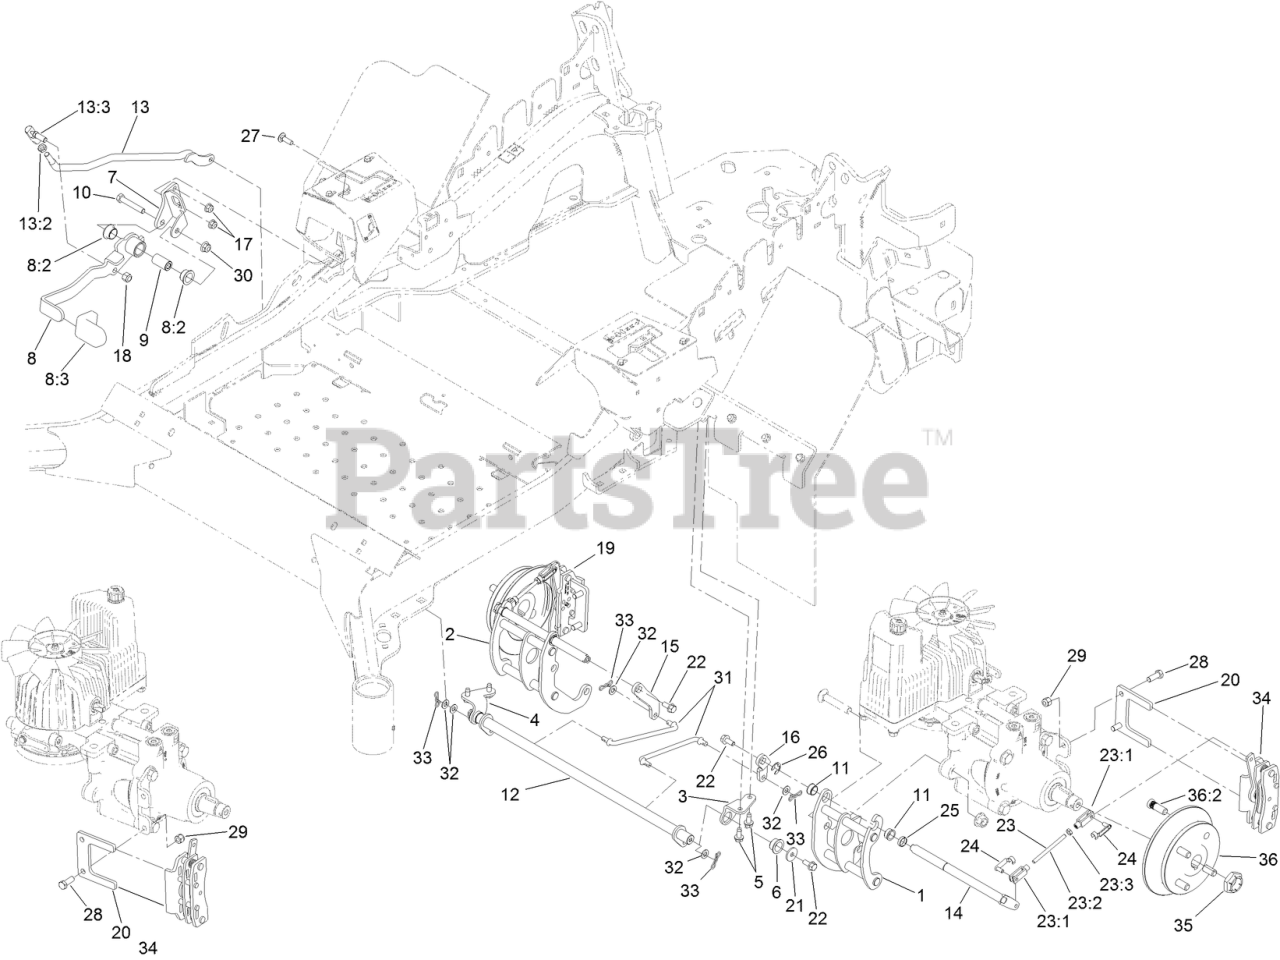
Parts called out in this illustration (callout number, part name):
1	MOUNT-BELLCRANK, LH
2	MOUNT-BELLCRANK, RH
3	MOUNT-PIVOT, LH
4	MOUNT-PIVOT, RH
5	SCREW-HWHTF
6	BUSHING-FLANGE
7	BRACKET-MOUNT
8	BRAKE LEVER ASM
8:2	BUSHING-FLANGE
8:3	GRIP-LEVER
9	HANDLE-PIVOT, BRAKE
10	SCREW-HH
11	BUSHING
12	SHAFT-CROSS
13	FRONT LINKAGE ASM
13:2	END-TIE ROD, RH
13:3	NUT-HJ
14	BELLCRANK,
15	ARM-INNER, RH
16	ARM-INNER, LH
17	NUT-HF, NI
18	NUT-LOCK
19	CALIPER-BRAKE, RH
20	PLATE-MOUNT, BRAKE
21	WASHER-FLAT
22	SCREW-HHF
23	REAR LINKAGE ASM
23:2	LINKAGE, REAR
23:3	NUT-JAM
24	PIN-CLEVIS, SPRING
25	SPACER
26	E-RING
27	BOLT-CARR
28	SCREW-HH,
29	NUT-LOCK
30	NUT-HF, NI
31	LINK-MID
32	WASHER-PLAIN
33	PIN-COTTER, LOCKING
34	CALIPER-BRAKE, LH
35	LOCKNUT
36	WHEEL HUB ASM
36:2	STUD-WHEEL
